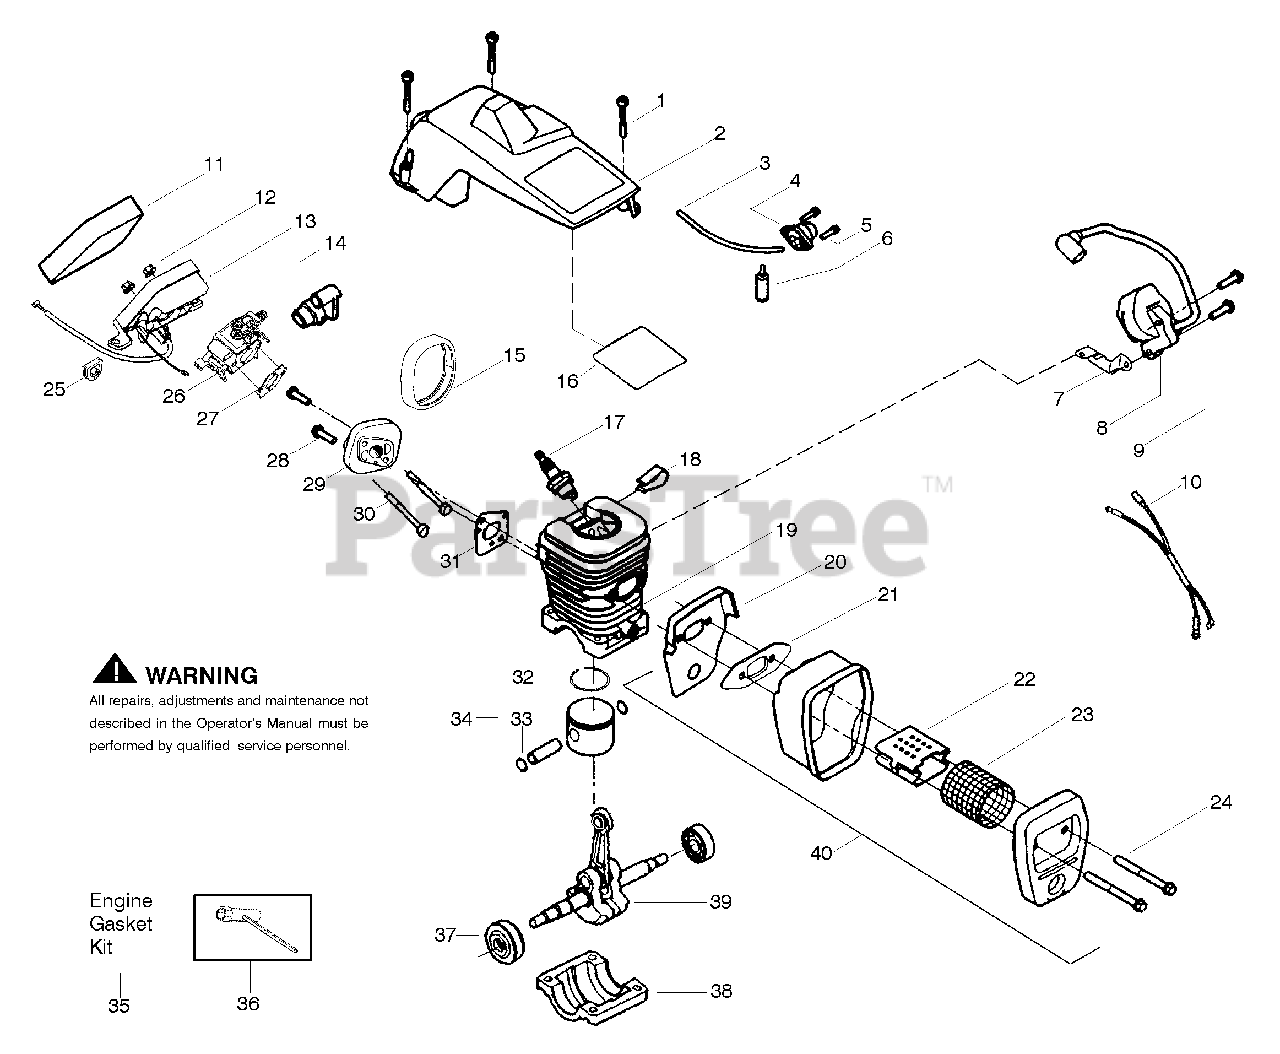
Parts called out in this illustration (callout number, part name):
2	Assy-Cylinder Shield
3	Kit-Fuel Line (Small)
4	Kit-Purge Bulb
6	Assy-Fuel Pick-up
7	Strap-Ground
8	Ignition Module
10	Assy-Wire Harness
11	Foam- Air Filter
13	Assy- Air Box
14	Grommet-Carb Adjust
15	Seal-Carb Adapter
16	Reflector-Heat
17	Spark Plug (RCJ-7Y)
18	Clip-High Tension Lead
19	Cylinder
20	Backplate-Muffler
21	Gasket-Muffler(kit)
22	Diffuser-Muffler
23	Screen-Spark
24	Bolt-Muffler
25	Grommet-Throttle Cable
26	Kit-Carburetor Zama (W-20)
26	Kit-Carburetor Walbro (WT-662)
27	Gasket-Carb. (kit)
29	Carb. Adapter
31	Gasket- Adaptor(kit)
32	Ring-Piston
33	Retainer-Piston Pin
34	Kit-Piston
35	Kit-Engine Gasket
36	Wrench-bar
37	Assy-Seal & Bearing
38	Cap-Crankcase
39	Assy-Crankshaft
40	Assy-Muffler
